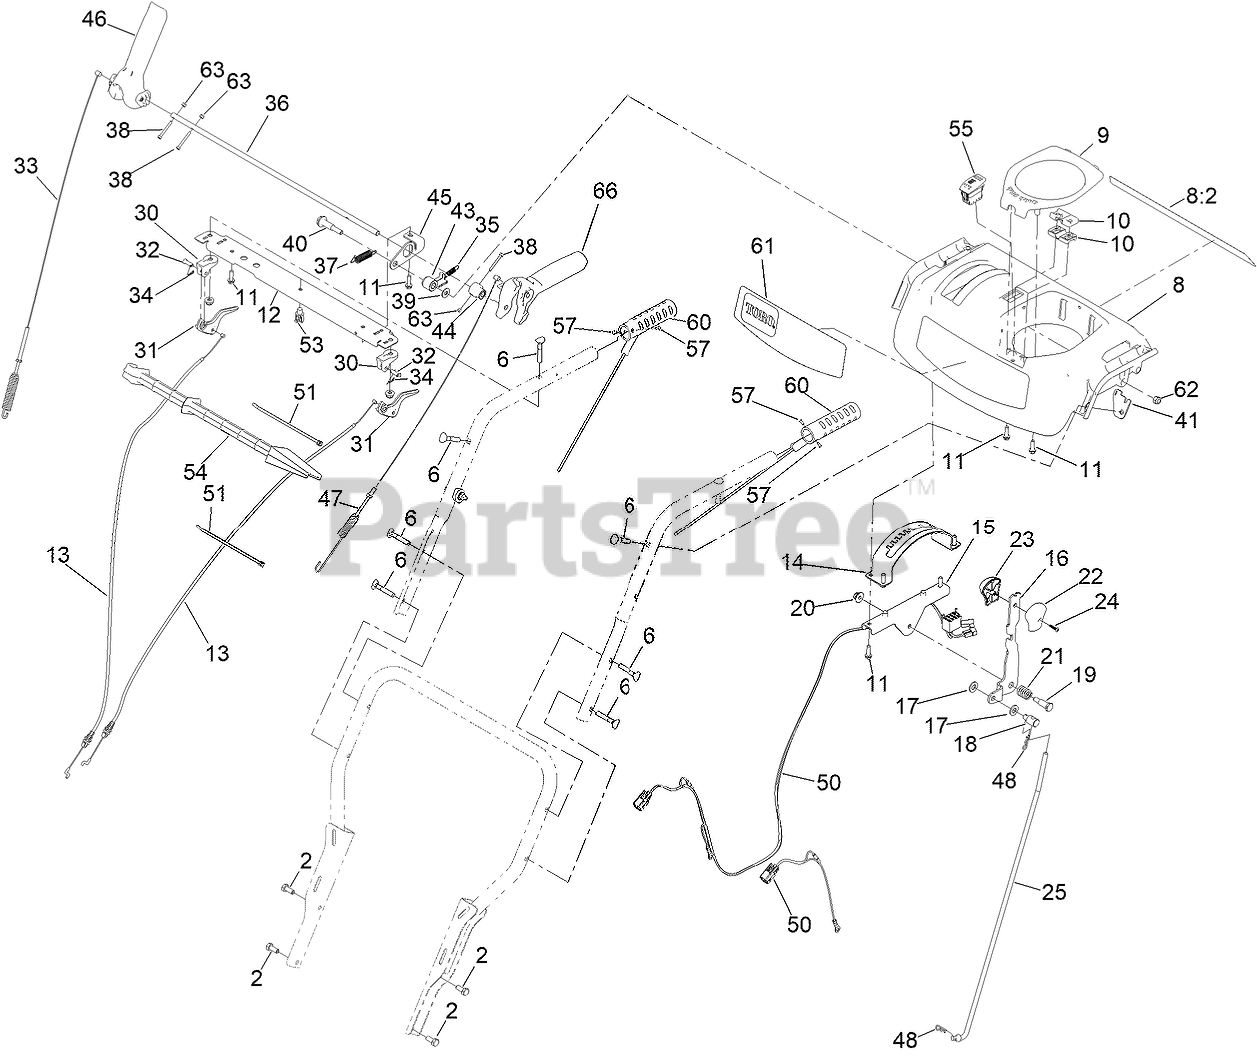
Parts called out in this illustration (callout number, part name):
2	SCREW-HH
6	SCREW-HANDLE
8	PANEL-CONTROL, ASSEMBLY
8:2	DECAL-SAFETY
9	COVER-QUICKSTICK
10	SUPPORT-ROD
11	SCREW-PLASTITE, HWH
12	BRACE-CONSOLE
13	CABLE-CLUTCH
14	GATE-SHIFT
15	BRACKET-SHIFT
16	SELECTOR-SPEED
17	WASHER-FLAT
18	TRUNNION-ROD
19	SCREW-SHOULDER, HH
20	NUT-HF
21	SPRING-COMPRESSION
22	KNOB-SHIFT, LH
23	KNOB-SHIFT, RH
24	SCREW-PPH
25	ROD-SHIFT
30	MOUNT-LEVER, CLUTCH
31	LEVER-CLUTCH
32	PIN-CLEVIS
33	CABLE-AUGER
34	PIN-HAIR
35	SPRING-LOCKOUT, HANDLE
36	ROD-LOCKOUT
37	SPRING-RETURN, LEVER
38	SCREW-HSH,SPL
39	WASHER-FLAT
40	SCREW-SHOULDER
41	PLATE-SPRING
43	LATCH, LOCKOUT
44	CAM-LOCKOUT
45	LINK-LOCKOUT
46	LEVER-CONTROL
47	CABLE-TRACTION
48	PIN-HAIR
50	HARNESS-WIRE, LED AND HAND WARMERS
51	TIE-CABLE
53	CLIP-TIE
54	STICK-CLEANOUT
55	SWITCH-ROCKER, ON-NONE-OFF (HEATER)
57	RIVET-POP
60	RED HEATED GRIP
61	DECAL-CONSOLE
62	NUT-HEX
63	NUT-LOCK ROHS
66	LEVER-CONTROL
